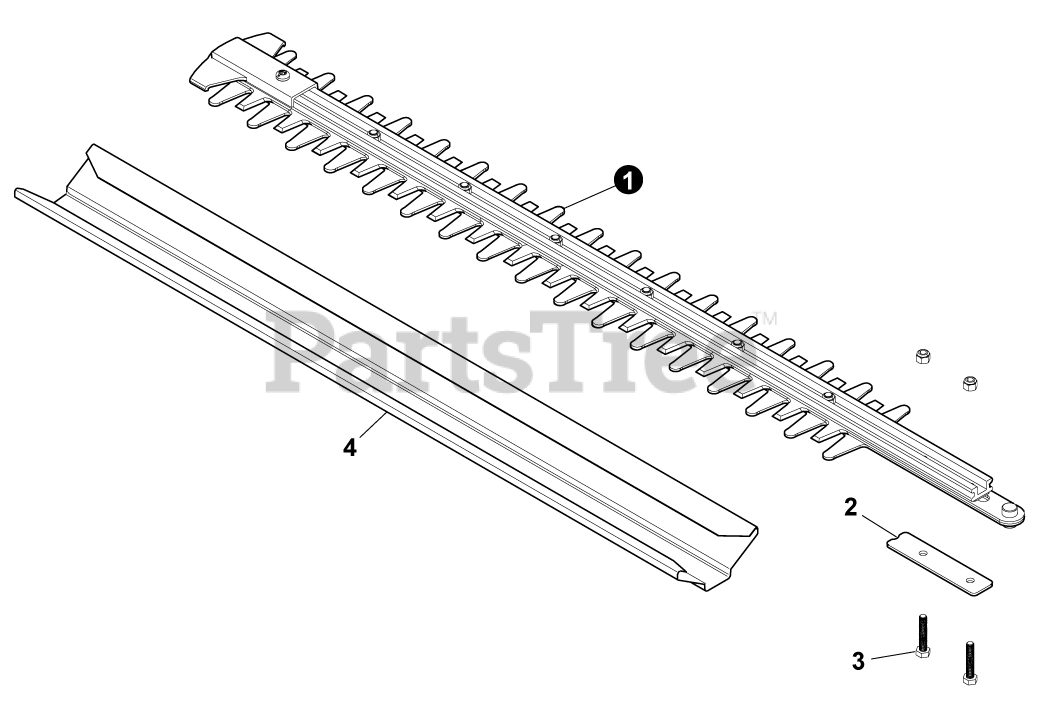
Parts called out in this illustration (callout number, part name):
1	BLADE ASSY
2	PLATE, BLADE RETAINING
4	SCABBARD
